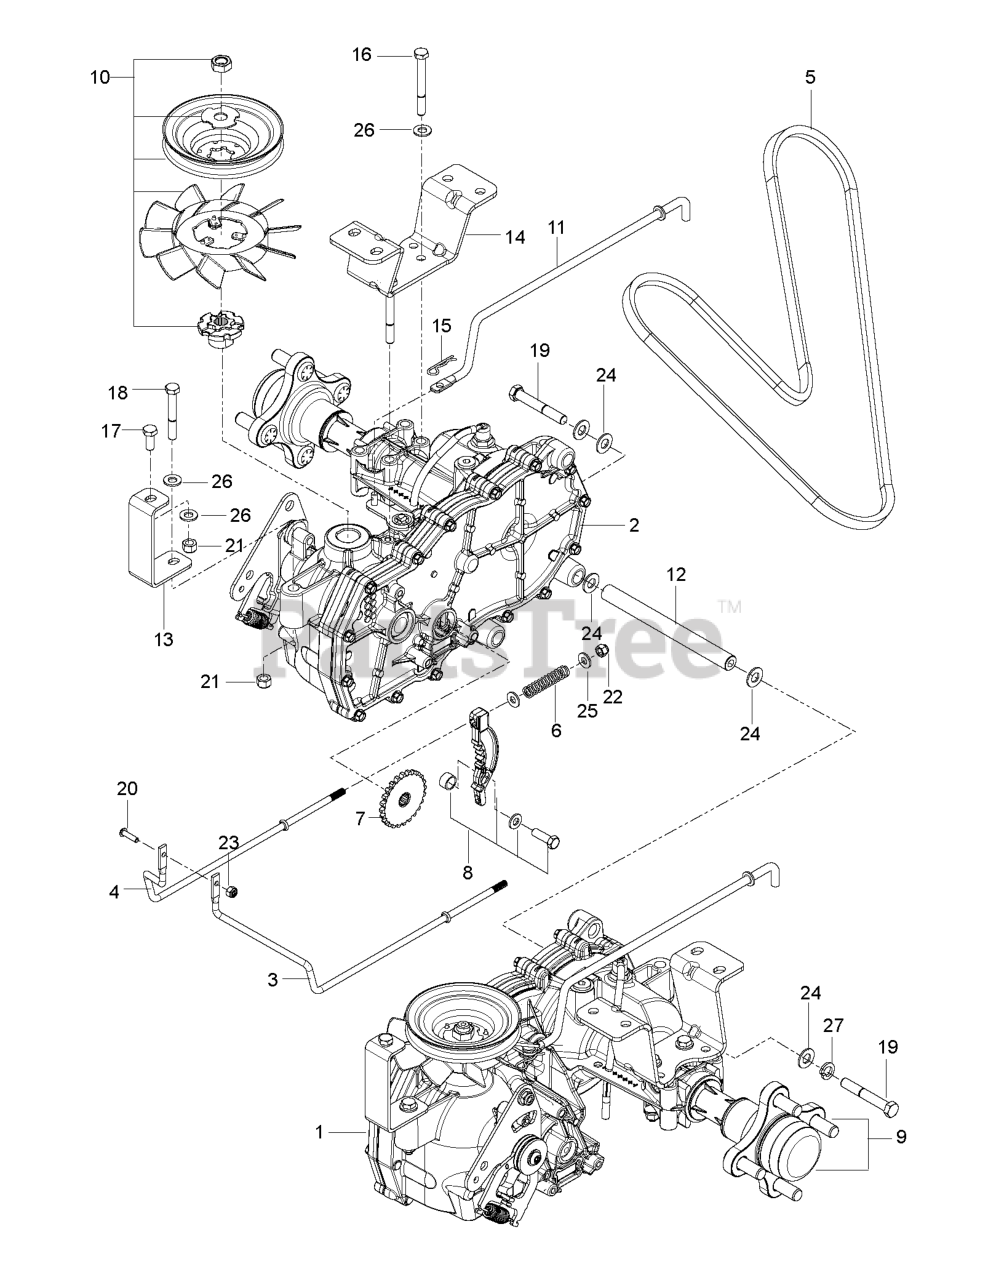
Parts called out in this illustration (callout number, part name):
1	HG_EZT, LT
2	HG_EZT, RT
3	LINKAGE.BRAKE.LT
4	LINKAGE, BRAKE RT
5	BELT, HYDRO PUMP
6	SPRING
7	HG_DISC COG BRAKE 51635
8	HG_KIT BRAKE ARM (EZT)
9	HG_KIT, HYDRO-GEAR HUB
10	KIT FAN/PULLEY 72137
11	LINKAGE, BYPASS, EZT
12	SPACER TUBE EZT
13	SUPPORT.FRONT.TRANS.PNTX431
14	BRACKET.EZT.MOUNT.REAR.PNTX431
15	HAIRPIN #2
16	BOLT HEX
17	HCS 5/16C X 3/4
18	BOLT.FIN HEX 5/16-18UNC X2 1/4
19	HCS 3/8C X 2 1/2
20	SCREW.TRSHD.SL.#10-24UNC X
21	NUT.71038.31-18.HEX.NYLOCK
22	RP_NUT 1/4-20 NYLOC
23	NUT 10-24 NYLOC
25	WASHER
26	WASHER
27	SLW 3/8 STD
